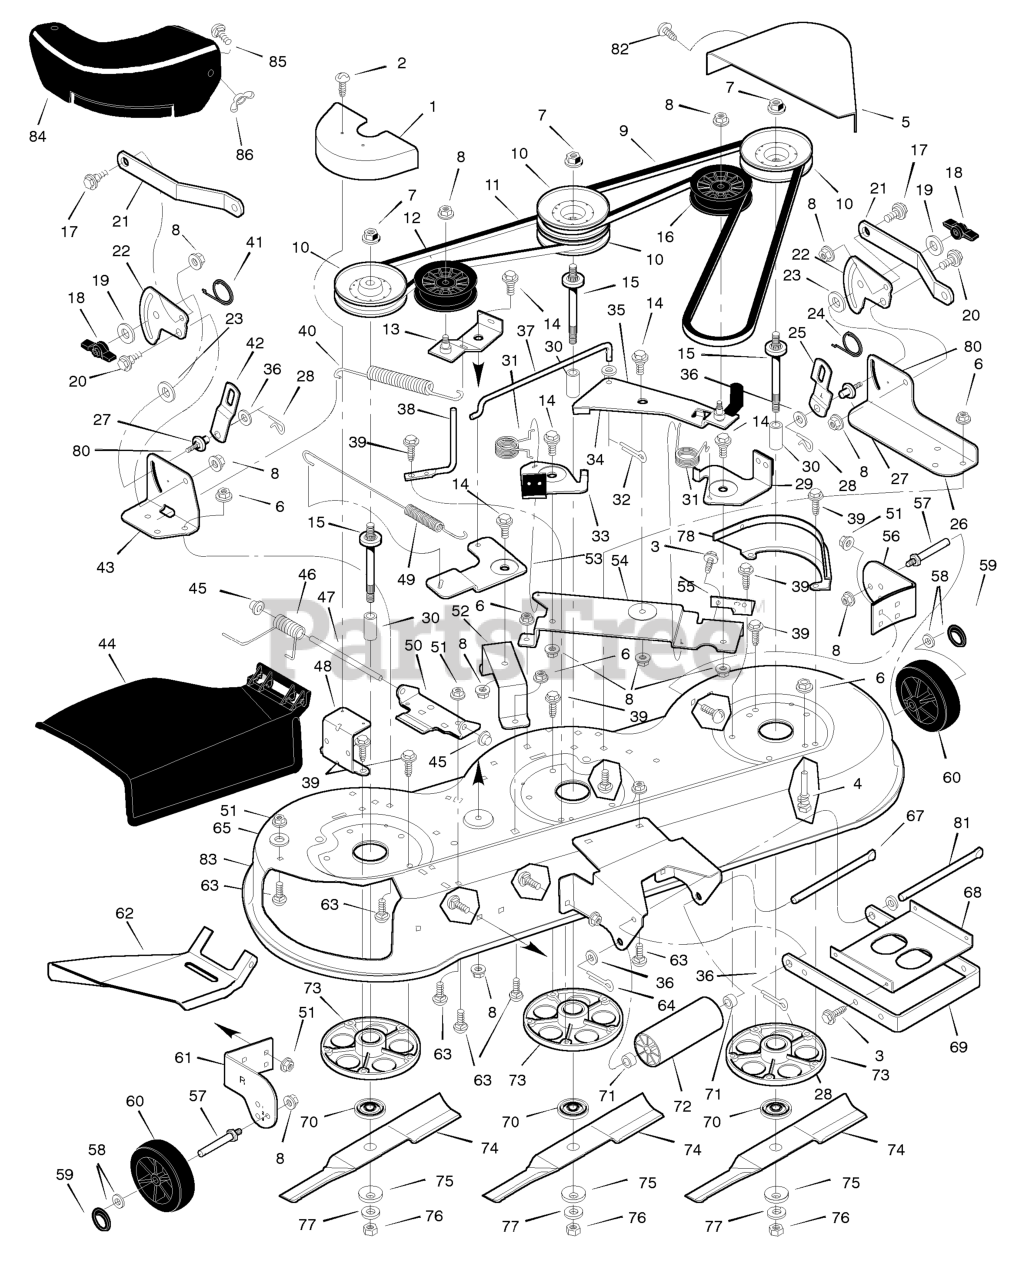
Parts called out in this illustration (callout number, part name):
1	Cover, Right Pulley
2	Screw
4	Guide, Belt
5	Cover, Left Pulley
6	Nut, Hex
7	Nut, Flange
8	Nut, Flange
9	Belt, Primary
10	Pulley
11	Belt, Secondary
12	Pulley, Idler
13	Arm, Idler
14	Bolt, Shoulder
15	Shaft, Splined
16	Pulley, Idler
17	Bolt, Shoulder
18	Knob
20	Bolt, Shoulder
21	Bracket, Rear Suspension
22	Plate, Suspension
23	Pad, Friction
25	Link, Left Lift
26	Bracket, Left Lift
27	Pin, Hanger
28	Pin, Hair
29	Brake Assembly, Left
32	Pin, Cotter
33	Brake Assembly, Right
34	Washer
35	Idler, Arm
37	Link, Bell Crank
38	Guide, Belt
39	Screw
40	Spring, Extension
41	Spring, Torsion
42	Link, Lift
43	Bracket, Right Lift
44	Deflector, Chute
45	Push On Cap
46	Spring, Torsion
47	Rod, Deflector
48	Bracket, Cover
49	Spring, Extension
50	Bracket, Hinge
51	Nut, Flange
52	Bracket, Bell Crank
53	Crank, Bell
54	Plate, Brake Arm
55	Bracket, Brake Plate
56	Bracket, Left Gauge Wheel
57	BOLT, Gauge Wheel
59	Ring, Locking
60	Wheel, Gauge
61	Bracket, Right Gauge Wheel
62	Deflector, Inside
63	Bolt, Carriage
64	Pin, Cotter
66	Bracket, Front Deck
67	Rod, Hanger
68	Stiffener
69	Bracket, Suspension
70	Adapter, Blade
73	Housing, Jackshaft
75	Washer, Belleville
78	Bracket, Pulley Cover
81	Rod, Hanger
83	Housing, Blade
84	Cover, Discharge
85	Bolt
86	Wingnut
